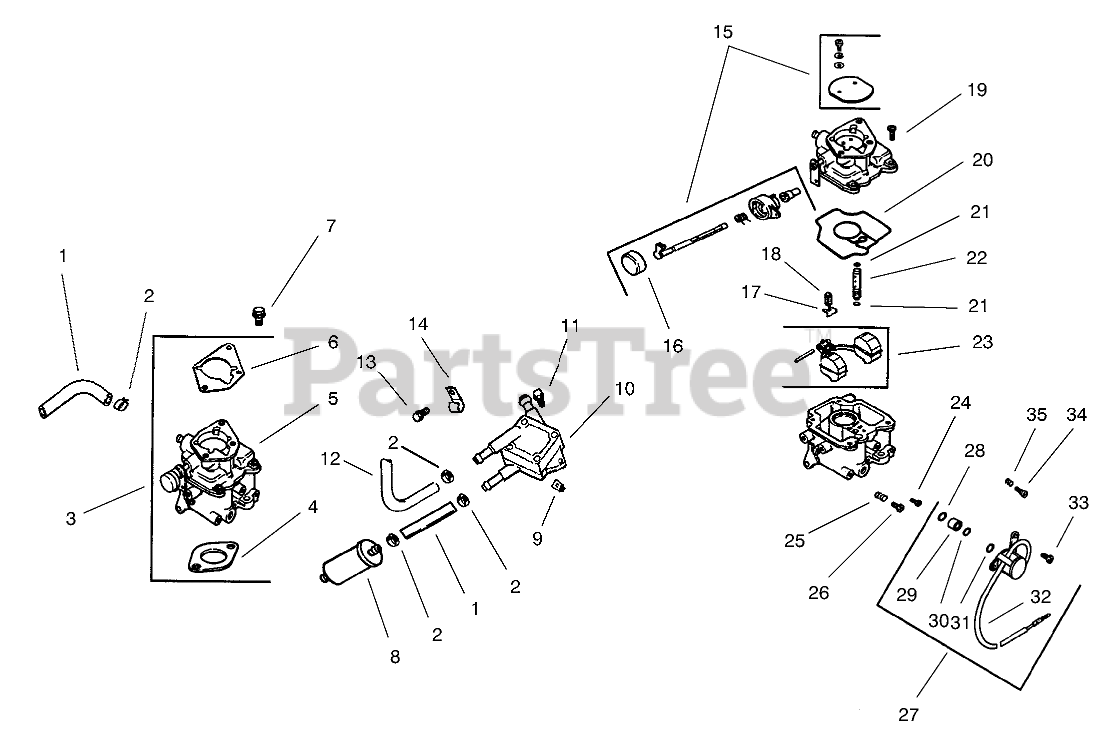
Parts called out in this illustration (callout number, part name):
1	Line fuel
2	Clamp
3	Kit, carburetor w/gasket (Includes 4-6)
4	Gasket
5	Carburetor assembly (Includes 15-35)(For information only not available separately)
6	Gasket
7	Screw
8	Filter-Fuel
9	Nut
10	Pump-Fuel
11	Screw
12	Line, fuel17"
13	Screw
14	Clamp
15	Kit, choke repair (Includes 16)
16	Cap-Choke Lever
17	Clip, cable
18	Valve-Inlet Needle
19	Screw
20	Gasket-Body,Carburetor
21	"O"Ring
22	Jet-Slow
23	Roat Repair Kit
24	Jet-Main
25	Spring-Idle Speed Adj.
26	Screw, idle adjusting
27	Kit, solenoid (Includes 28-33)
28	O-Ring
29	Seat-Solenoid
30	O-Ring
31	O-Ring
32	Solenoid
33	Screw
34	Needle, idle
35	Spring-Idle Adj.
